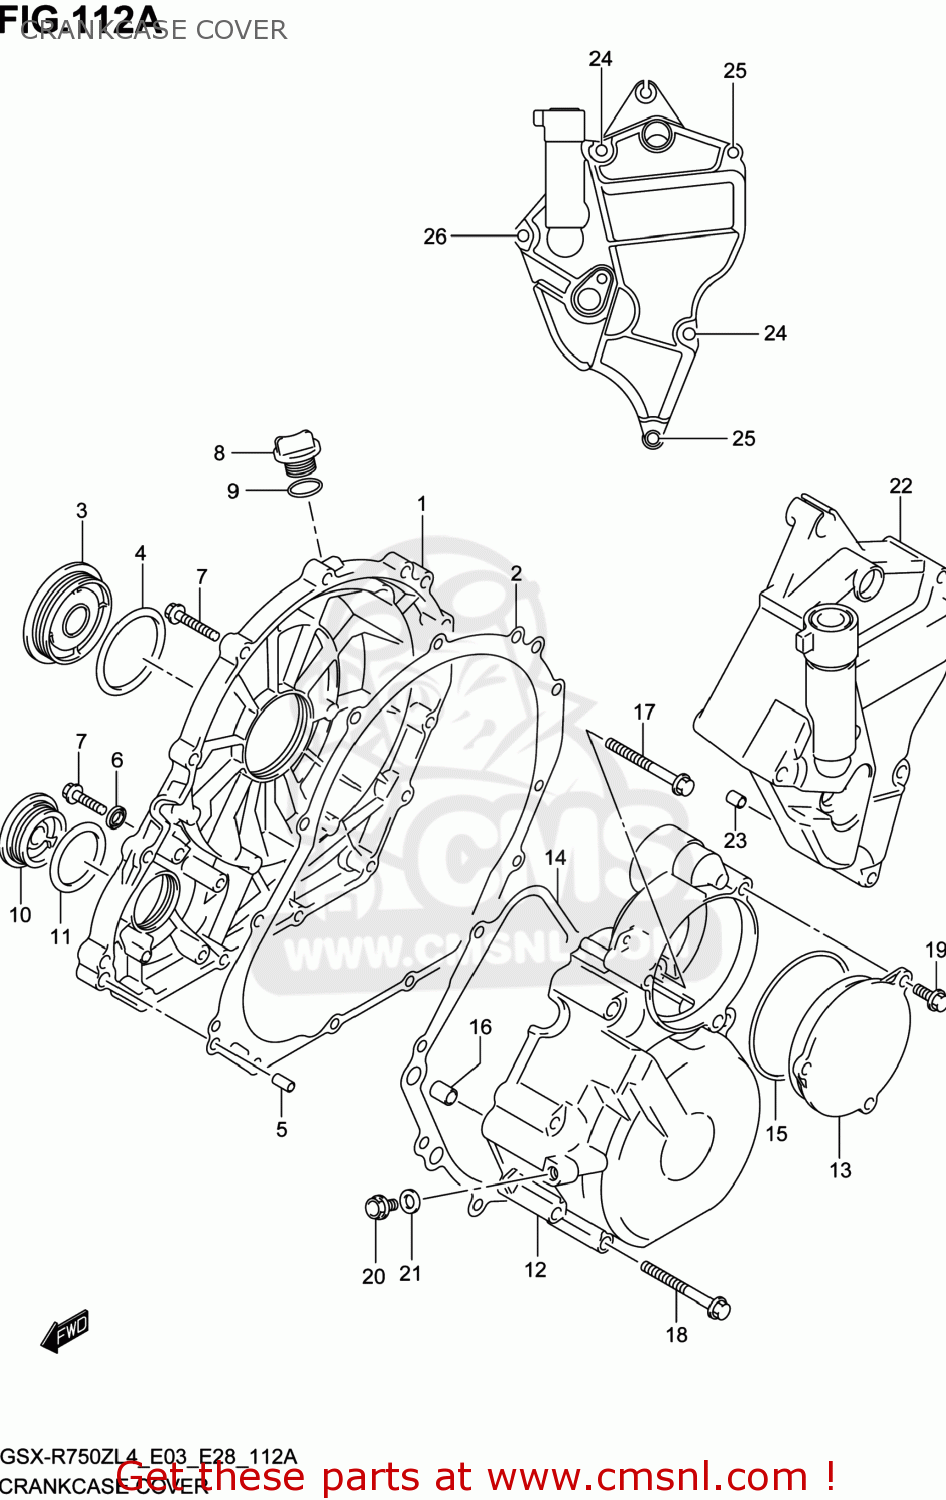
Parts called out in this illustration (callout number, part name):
1	COVER,CLUTCH
2	GASKET,CLUTCH COVER (NAS)
3	CAP,CLUTCH RELEASE ADJUST
4	O RING
5	PIN
6	GASKET(5.8X13X1.2) (NAS)
7	BOLT(6X30)
8	PLUG,ENGINE OIL FILLER
9	O RING(D:3.1,ID:16.8)
10	PLUG
11	O RING(D:3.1,ID:32.7)
12	COVER,GENERATOR
13	CAP,STARTER IDLE GEAR
14	GASKET,GENERATOR COVER (NAS)
15	O RING(D:2.6,ID:67.1)
16	PIN
17	BOLT(6X25)
18	BOLT(6X50)
19	BOLT(6X16)
20	BOLT(6X12)
21	GASKET(6.2X13X1.2) (NAS)
22	COVER,ENGINE SPROCKET
23	PIN
24	BOLT(6X45)
25	BOLT(6X65)
26	BOLT(6X75)
